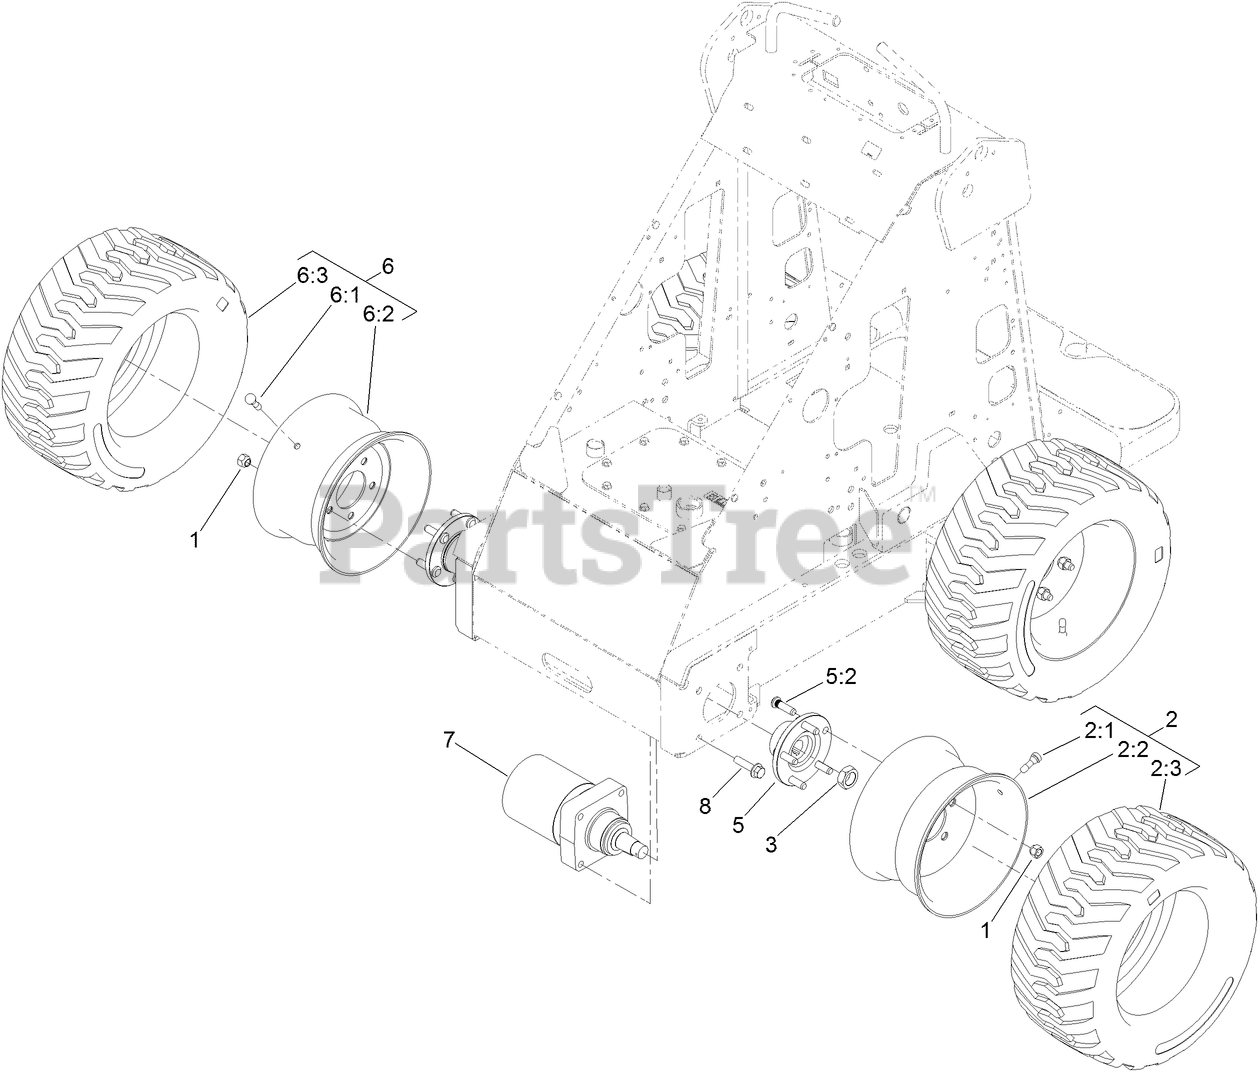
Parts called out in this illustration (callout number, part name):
1	NUT-LUG
2	LH WHEEL AND TIRE ASM
2:2	WHEEL
3	NUT-LOCK
5	HUB ASM
5:2	STUD-TYPE, DRIVE
6	RH WHEEL AND TIRE ASM
6:2	WHEEL
7	HYD MOTOR ASM
8	SCREW-HHF
